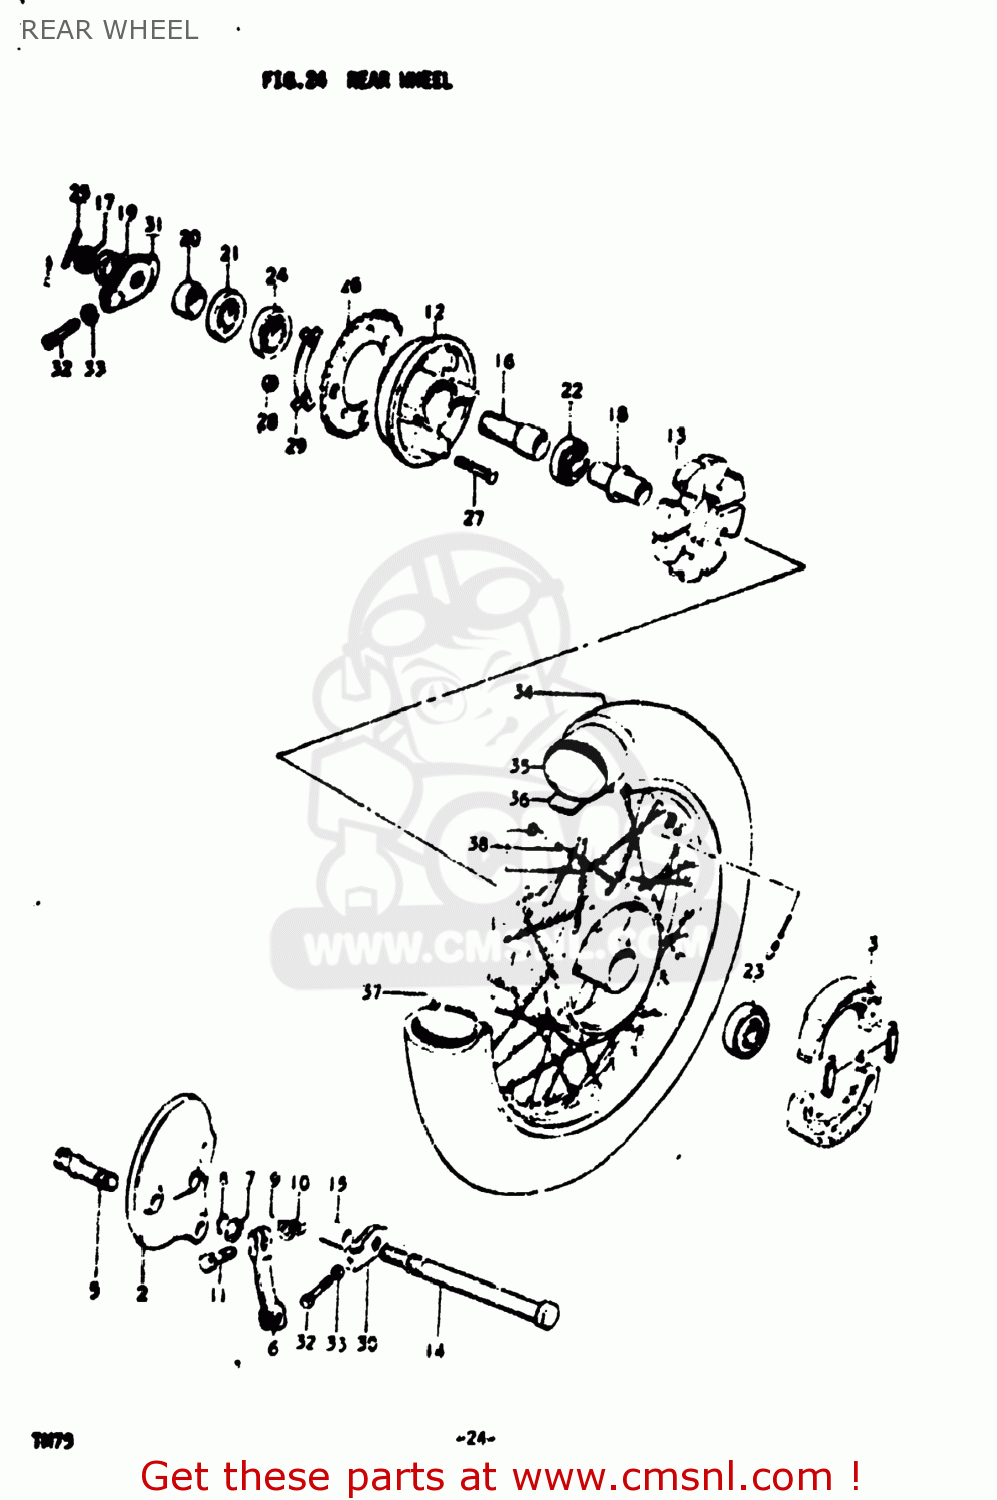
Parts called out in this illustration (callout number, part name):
1	HUB,REAR
2	PANEL,REAR HUB
3	SHOE,BRAKE
4	SPRING(L:34)
5	CAM,FR BRAKE
6	LEVER,REAR BRAKE CAM
7	WASHER(12.5X20X1)
8	O RING(D:2.5,ID:11.4)
9	WASHER
10	NUT
11	BOLT
12	DRUM,REAR SPROCKET MOUNT
13	CUSHION,REAR DRUM
14	AXLE,REAR
15	SPACER(12.2X22X30.5)
16	SHAFT,RR SPROCKET DRUM
17	NUT
18	SPACER,REAR HUB BEARING
19	NUT
20	SPACER(17X25X10.5)
21	SEAL OIL(25X40X6)
22	BEARING, LH
23	BEARING, RH
24	BEARING
25	COTTER PIN
26	SPROCKET,REAR
27	BOLT(8X33.5)
28	NUT
29	WASHER
30	ADJUSTER,CHAIN,R
31	ADJUSTER,CHAIN,L
32	BOLT(6X38)
33	NUT
34	TIRE
35	TUBE,INNER
36	PROTECTOR,INNER TUBE
37	RIM,FRONT WHEEL (1.40X14)
38	SPOKE SET,REAR
